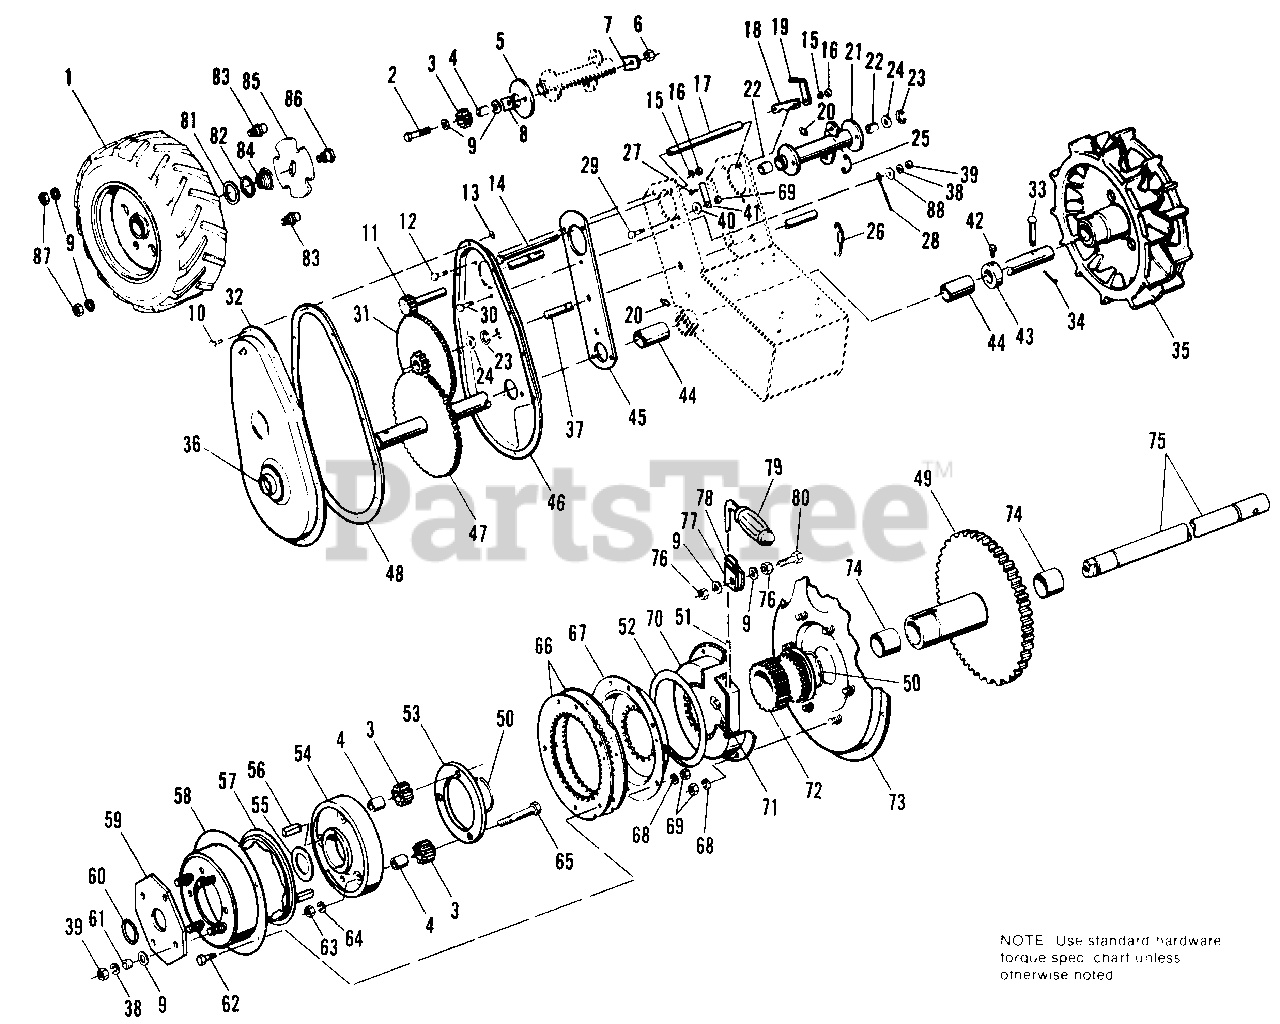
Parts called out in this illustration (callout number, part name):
1	WHEEL & TIRE ASSY.
2	CAPSCREW, Hex Hd., L.H. Thd., 3/8-16 x 1-1/2
3	PINION, Reverse (Qty. 1 used on 990482 & 990558)
4	SPACER (Qty. 1 used on 990482 & 990558)
6	NUT, Hex, Full, L.H. Thd., 3/8-16
7	PLATE, Lock
8	SPACER, Reverse Pinion
9	WASHER, Plain, 5/16 (Qty. 6 used on 990482 & 990558)
10	SCREW, Self Tapping. #10 X 1/2
11	SHAFT ASSY., Pulley
12	CAPSCREW, Hex Hd., 5/16-18 x 5/8
13	NUT, Speed
14	BOLT, Frame
15	LOCKWASHER, 5/16
16	NUT, Hex, Full, 5/16-18
17	SPACER, Frame
18	PLATE, Friction, Stop
19	GUIDE, Clutch Wire (990482 & 990558 Only)
20	FITTING, Grease (Qty. 2 used on 990482 & 990558)
21	HOUSING ASSY., Bearing
23	RING, Retaining
25	EXTENSION, Spring
26	SPRING, Reverse Lever
27	SCREW, Self Tapping, #10 x 3/8
28	PIN, Lock
29	CAPSCREW, Hex Hd., 1/4-20 x 5/8
30	CAPSCREW, Hex Hd., 3/8-16 x 1
31	GEAR ASSY.
32	COVER ASSY, Gear Case
33	PIN
34	PIN, Quick
35	WHEELS, Steel
36	WASHER, Retaining
37	SHAFT, Intermediate
38	LOCKWASHER, 3/8 (Qty. 1 used on 990482 & 990558)
39	NUT, Hex, Full, 3/8-16 (Qty. 1 used on 990482 & 990558)
40	WASHER, Plain, 1/4
41	DETENT, Neutral
42	SETSCREW, 5/16-18 x 1/2
43	COLLAR, Set
46	CASE, Gear
47	AXLE & GEAR ASSY. (990482 Only)
47	AXLE & GEAR ASSY. (990558 Only)
48	GASKET, Gear Case
49	GEAR & TUBE ASSY. (990483 & 990559 Only)
50	RING, Snap (990483 & 990559 Only)
51	ROD ASSY., Shift (990483 & 990559 Only)
52	SEAL (990483 & 990559 Only)
53	RING, Bolt (990483 & 990559 Only)
54	SPIDER (990483 & 990559 Only)
55	WASHER (990483 & 990559 Only)
56	KEY (990483 & 990559 Only)
57	PLATE, Thrust (990483 & 990559 Only)
58	CARRIER ASSY. (990483 & 990559 Only)
59	PLATE, Axle, R.H. (990483 & 990559 Only)
60	RING, Snap (990483 & 990559 Only)
61	SPACER (990483 & 990559 Only)
62	CAPSCREW, Hex Hd., 1/4-20 x 5/8 (990483 & 990559 Only)
63	NUT, Hex, Full, 3/8-24 (990483 & 990559 Only)
64	LOCKWASHER, Ext., 3/8 (990483 & 990559 Only)
65	CAPSCREW, Hex Hd., 3/8-24 x 1-1/2 (990483 & 990559 Only)
66	GEAR, Ring (990483 & 990559 Only)
67	COVER ASSY. (990483 & 990559 Only)
68	LOCKWASHER, 1/4 (990483 & 990559 Only)
69	NUT, Hex, Full, 1/4-20 (990483 & 990559 Only)
70	HOUSING ASSY. (990483 & 990559 Only)
71	BLOCK, Shift (990483 & 990559 Only)
72	GEAR ASSY., Sun (990483 & 990559 Only)
73	COVER ASSY., Gear Case (990483 & 990559 Only)
74	BEARINGS (990483 & 990559 Only)
75	SHAFT, Axle (990483 Only)
75	SHAFT, Axle (990559 Only)
76	LOCKNUT, Hex, 5/16-18 (990483 & 990559 Only)
77	GUIDE, Rod (990483 & 990559 Only)
78	LINER (990483 & 990559 Only)
79	GRIP (990483 & 990559 Only)
80	CAPSCREW, Hex Hd., 5/16-18 x 1-1/4 (990483 & 990559 Only)
81	WASHER (990558 & 990559 Only)
82	RING, Retaining (990558 & 990559 Only)
83	STUD (990558 & 990559 Only)
84	SPRING (990558 & 990559 Only)
85	PLATE (990558 & 990559 Only)
86	BOLT, Shoulder (990558 & 990559 Only)
87	LOCKNUT, Hex, 3/8-16
88	WASHER, Plain, 3/8
